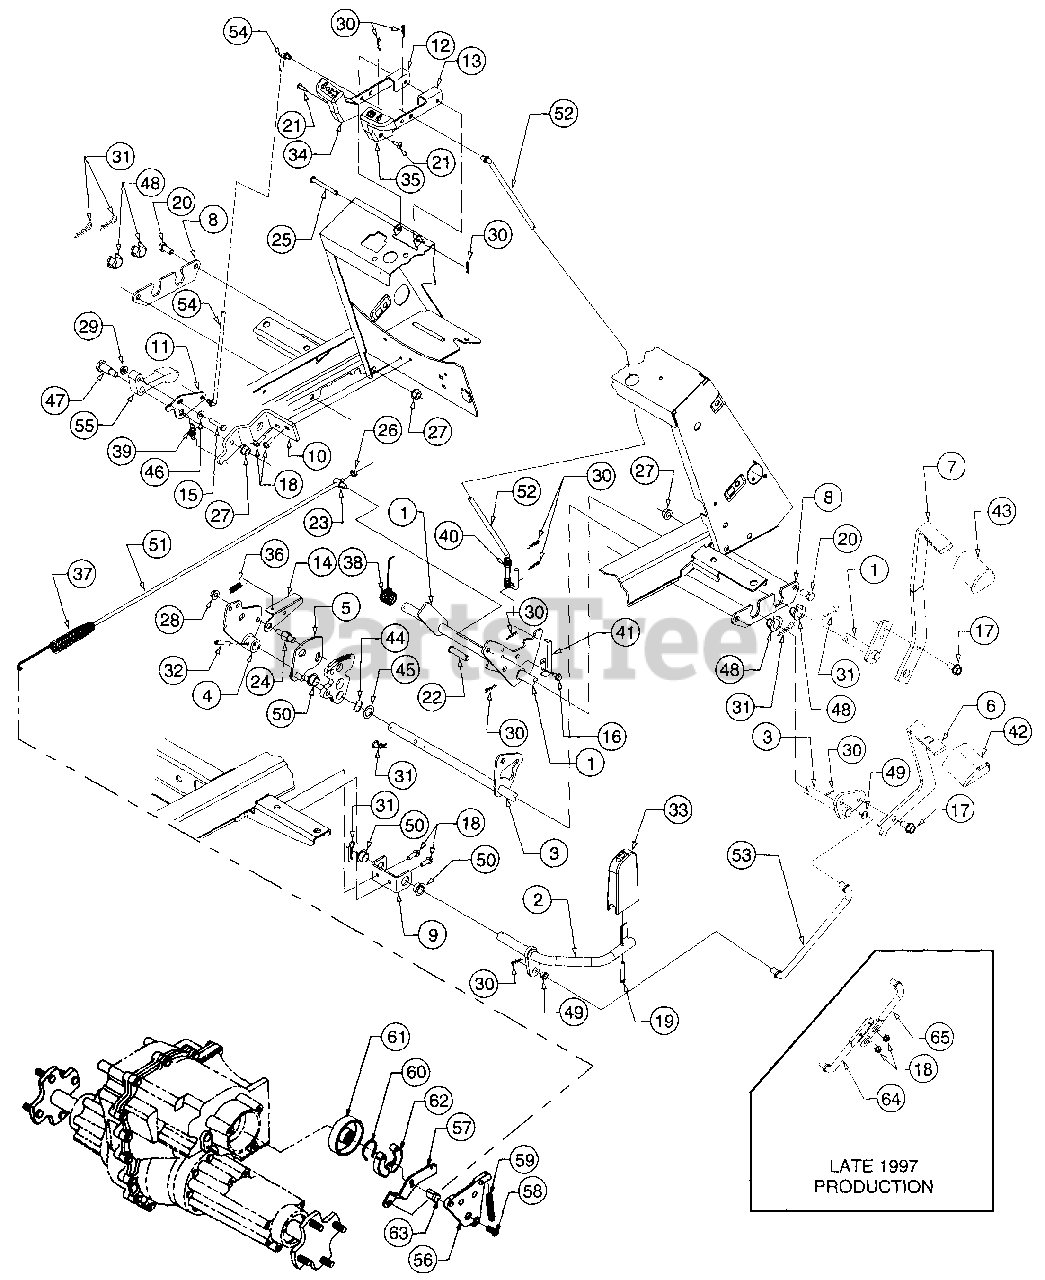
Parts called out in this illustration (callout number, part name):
1	Shaft Assy, Brake
4	Cam Assy, Control
5	Plate Assy, Disengagement
6	Pedal, Forward
7	Pedal, Brake
8	Plate, Bearing Mounting
10	Bracket, Cruise
11	Plate, Rod Adjustment
15	Screw, Hex Cap, 1/4-20 x 1.25
16	Screw, Hex Wshr Tap 1/4-20 x .5
17	Screw, Hex Wshr Tap 3/8-16 x .75
18	Screw, Hex Wshr Tap 1/4-20 x .75
19	Screw, Truss Mach, #12 x 1.5
20	Screw, Hex Cap, 3/8-16 x .75 GR5
21	Screw, Phil Hd Pan, #10-24 x .75
22	Pin, Clevis, 3/8 x 1.62
23	Ferrule, Adjustment, 1/4-20 Thrd
24	Stud, Actuator
25	Pin, Clevis, .25 x 2.38 Lg
26	Nut, Hex Sems, 1/4-20
27	Nut, Hex Flange Lock, 3/8-16
28	Nut, Hex Flange Lock, 5/16-18
29	Nut, Hex Flange Lock, 1/4-20
30	Pin, Int Cotter, 5/16 Dia x 1.12 Lg
31	Pin, Int Cotter, 3/8 Dia x 1.62
32	Pin, Spiral Spring, 1/4 x 1.5
33	Pedal, Reverse
34	Knob, Cruise
35	Knob, Brake Lock
36	Spring, Extension. .38 OD x 2.1
37	Spring, Extension
38	Spring, Torsion
39	Spring, Ext, .437 OD x 1.32
40	Spring, Compression, .50 x 2.23
41	Spring, Switch Actuator
42	Pad, Forward Foot Control
43	Pad, Brake Foot
44	Washer, Wave, .625 x .885 x .015
45	Washer, Flat, .635 x 1.0 x .020
46	Washer, Flat, 1/4 x .63 x .051
47	Shoulder Bolt, .50 OD x .840
48	Bearing, Hex Flange Split
49	Bearing, Flange, .375 x .58 x .25
50	Bearing, Flange, .626 x .93 x .344
51	Rod, Brake
52	Rod, Parking Brake
53	Rod, Connecting
54	Rod, Cruise
55	Latch, Cruise
56	Plate, Brake
57	Arm, Brake
58	Screw, Low Hd Cap, 3/8-16 x .75
59	Spring, Compression
60	Spring, Brake
61	Drum, Brake
62	Shoe, Brake
63	Actuator, Brake Shoe
64	Rod, Rear Connecting
65	Rod, Front Connecting
